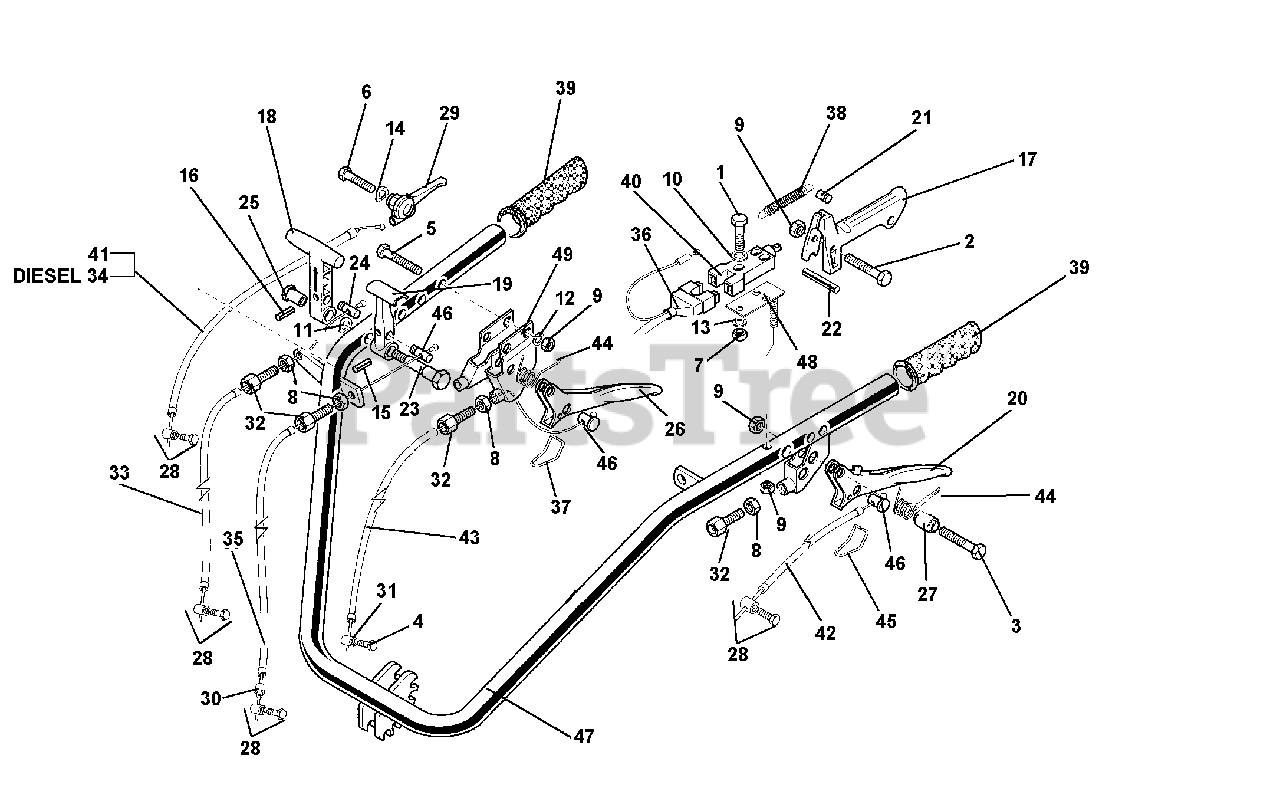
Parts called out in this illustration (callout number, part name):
1	SCREW TE M4X25
2	SCREW TE M6X45
3	SCREW M6X25
4	SCREW TE M6X16
5	SCREW M6X40
6	SCREW TE M8X40
9	NUT, SELF LOCKING M6
10	FLAT WASHER 4,3
12	WASHER, LOCK 6,4
13	LOCK WASHER B 4,3
14	WASHER, LOCK 8,4
15	PIN, LOCKING 4X20
16	PIN, LOCKING M4X20
17	MOTOR STOP LEVER
18	REVERSER LEVER
19	LEVER DIFFERENTIAL LOCKING
20	CLUTCH LEVER
22	LEVER STOP FOR MOTOR STOP
24	DRILLED PIN
25	DRILLED PIN
27	LEVER SPACER
28	CLAMP, CABLE
29	LEVER, ACCELERATOR
31	PIN, CABLE CLAMP
32	SCREW, ADJUSTING M8
33	CABLE, CLUTCH
34	THROTTLE CABLE, DIESEL
35	CABLE, DIFFERENTIAL LOCK OUT
36	SWITCH WIRING HARNESS
40	STOP SWITCH
41	THROTTLE CABLE
42	CLUTCH CABLE
43	CABLE, CLUTCH
44	LEVER SPRING
47	HANDLE ASSEMBLY
48	SWITCH PLATE
49	COUPLING FOR DOUBLE LEVER
